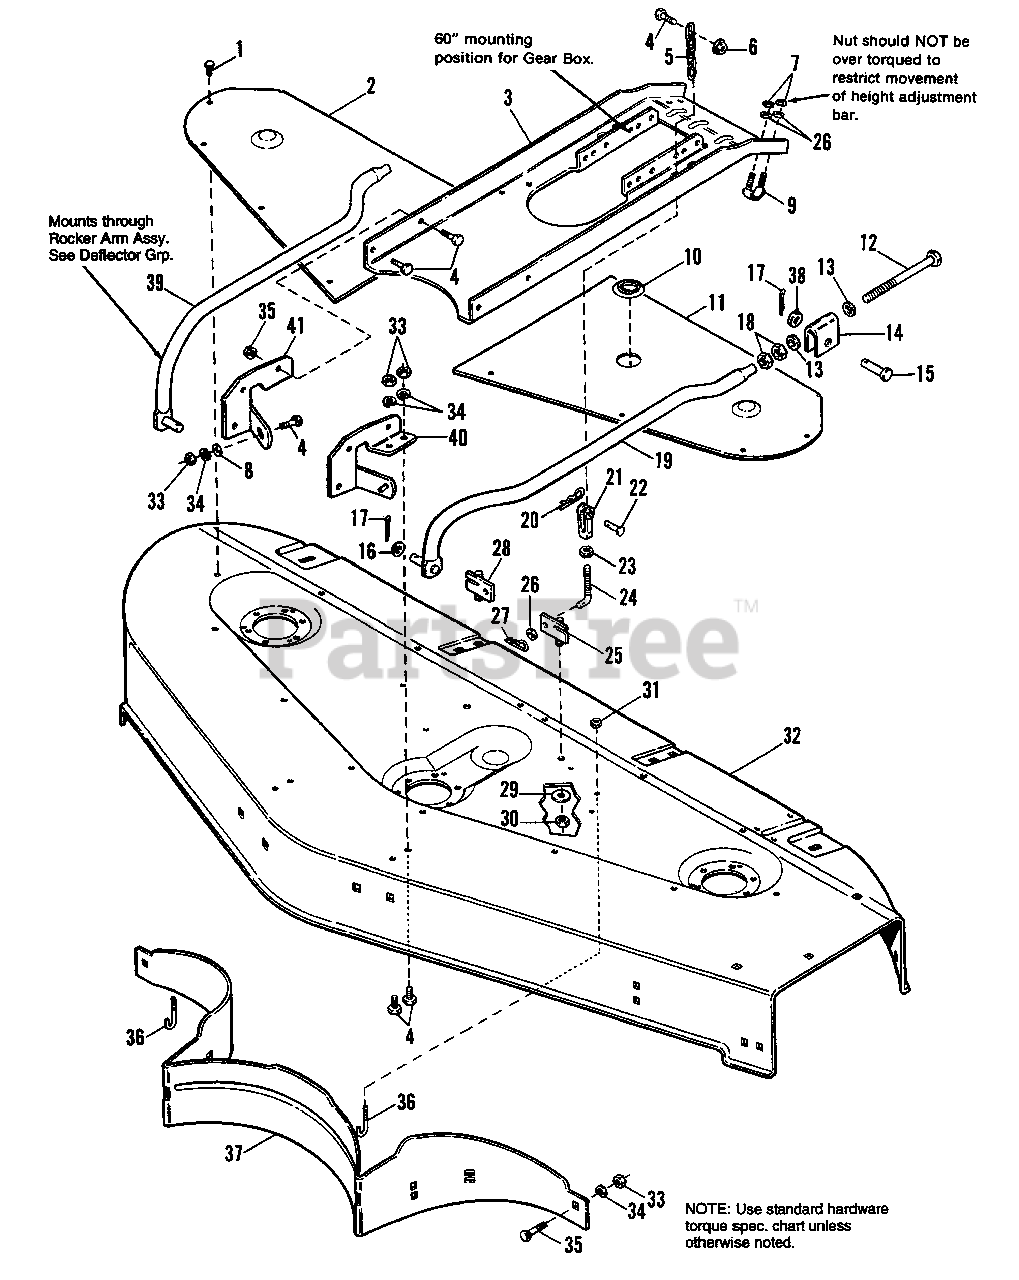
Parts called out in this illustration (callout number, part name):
1	SCREW, Hex, Taptite 1/4-20 x 3/8
2	COVER, Mower, R.H.
3	SUPPORT, "U" Channel
4	CAP SCREW, Hex Hd., 3/8-16 x 1
5	CHAIN, 5 Link
5	CHAIN, 6 Link
6	NUT, Hex, Flange lock, 3/8-16
7	NUT, Centerlock, 5/16-18
8	WASHER, 13/32
10	PLUG, Mower Cover, L.H.
11	COVER, Mower, L.H.
12	CAPSCREW, Hex, 5/8-18 x 5-1/2
13	WASHER, 5/8
14	TRUNNION
15	PIN, Trunnion
16	WASHER, 5/8
17	PIN, Cotter, 1/8-1
18	NUT, Hex, Jam, 5/8-18
19	Arm ASSY., L.H.
20	CLIP, Hair Pin
21	CLEVIS, Lift
22	PIN, Rivet, Clevis
23	NUT, Hex, Jam, 5/16-18
25	BRACKET ASSY., Lift L.H.
26	WASHER, Plain, 5/16 x 3/4 x 1/16
27	CLIP, Hair Pin
28	BRACKET ASSY., Lift, R.H.
29	WASHER, Plain, 13/32 x 1-1/2 x 1/8
30	NUT, Hex, Centerlock, 3/8-16
31	NUT, Hex, Centerlock, 5/16-18
32	HOUSING, 60" Mower
33	NUT, Hex, 3/8-16
34	LOCKWASHER, 3/8
35	NUT, Hex, Whizlock 3/8-16
37	BAFFLE, Mower
38	WASHER, Plain, 17/32
39	ARM ASSY., R.H.
40	BRACKET ASSY., L.H.
41	BRACKET ASSY., R.H.
